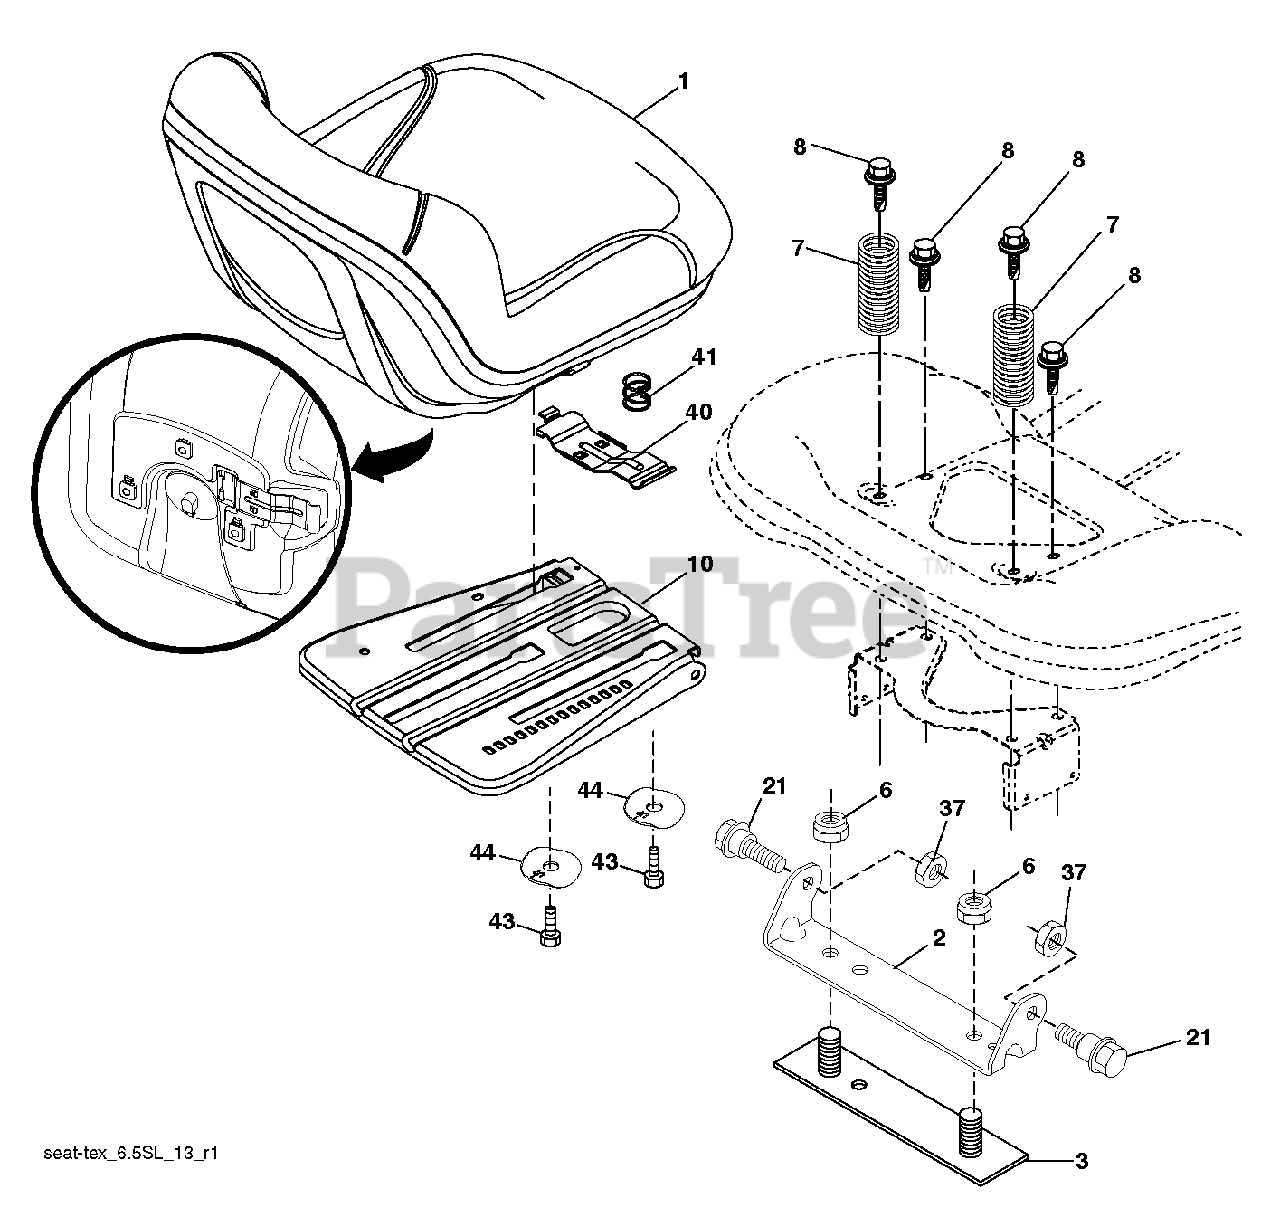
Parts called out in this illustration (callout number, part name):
1	SEAT.TH150.MS498.GRY.HUSQ.TEX
2	BRKT.PIVOT.FENDER
3	STRAP
6	NUT
7	SPRING.COMPRESS.SEAT.
8	BOLT, 5/16-18 X 1 3/4
10	Seat Slide Plate, Pnt
21	BOLT.5/16-18X5/8.SHOULDER
37	NUT.71038.31-18.HEX.NYLOCK
40	HANDLE.SLIDE.SEAT.TEX.BLACK
41	SPRING.LATCH.SEAT.TEX
44	Winged Washer, 38Id 1
